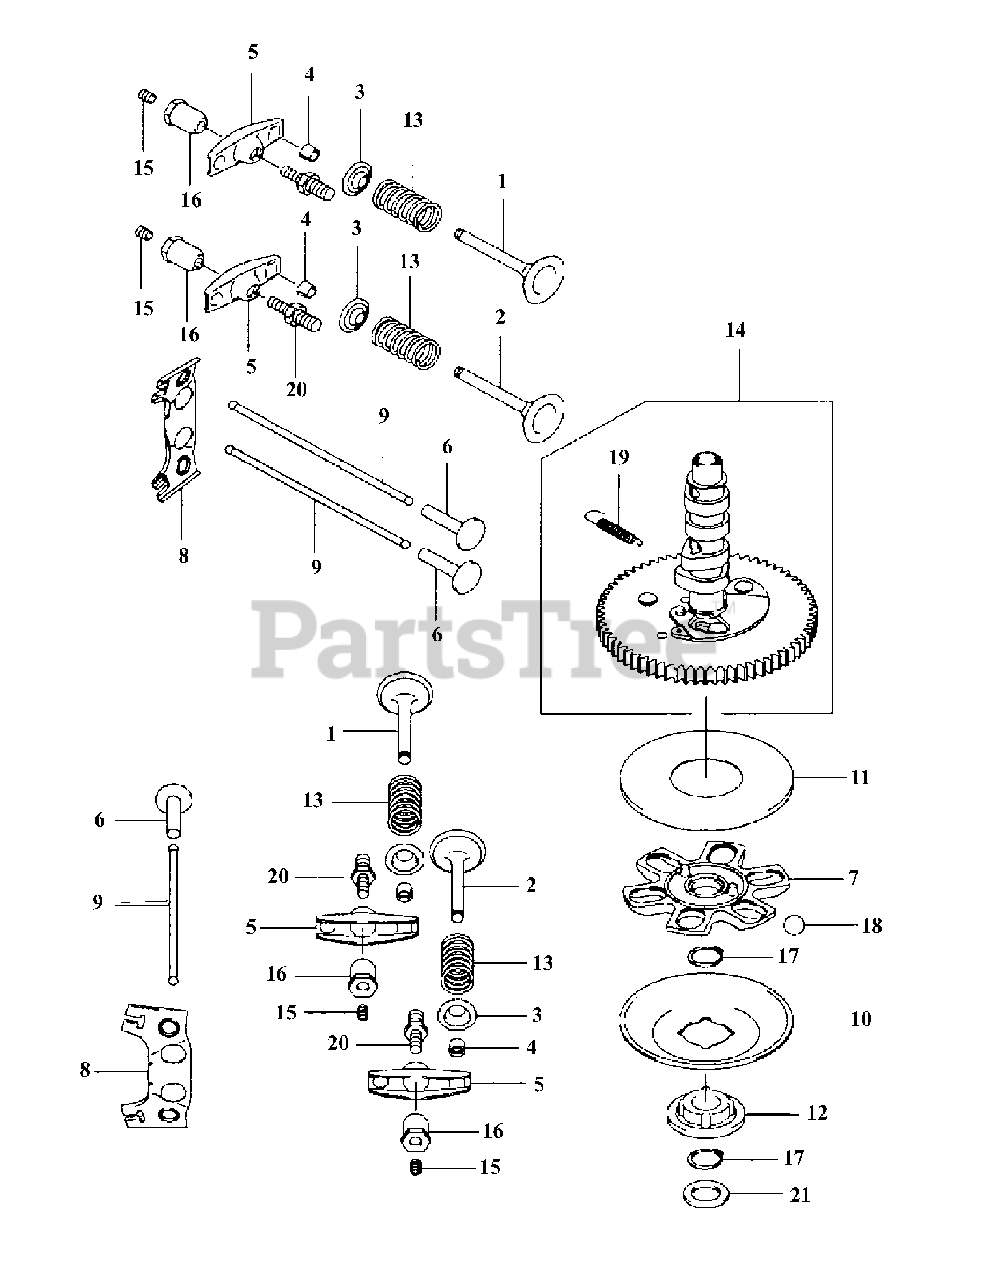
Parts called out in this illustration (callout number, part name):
2	Valve-Exhaust
3	Retainer-Valve Spring
13	Spring-Engine Valve
14	Camshaft comp
17	Ring-Snap
18	Ball
19	Spring
